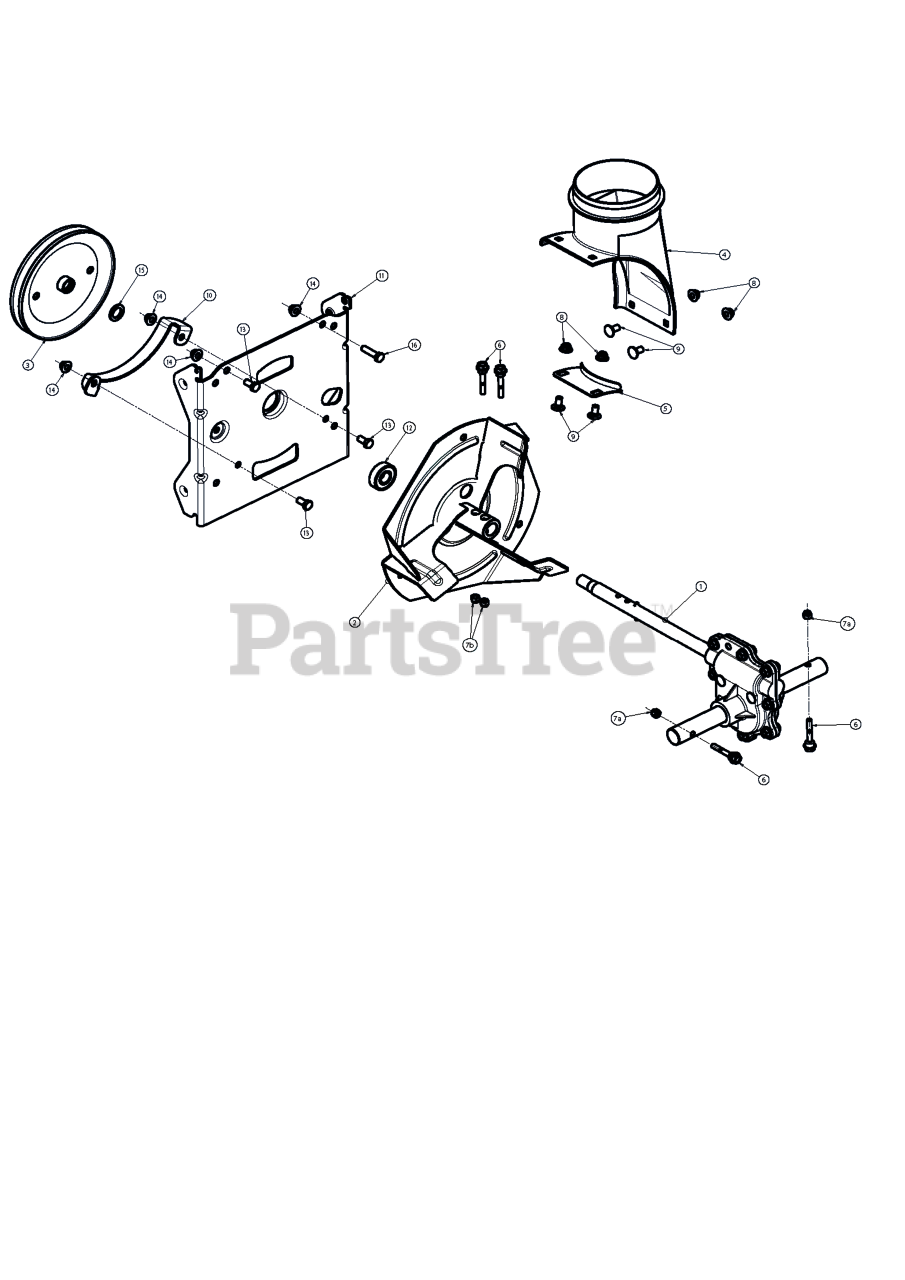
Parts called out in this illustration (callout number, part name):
1	GEAR BOX ASM ALUM
2	IMPELLER.STEEL.SNOW.BLACK
3	PULLEY SCREW ON 7.3
4	CHUTE.DISCHARGE.BASE
5	BRACKET, CORNER DISCHARGE
6	RP_SCREW.1/4-20 X 1-13/16 SHEA
7	LOCKNUT.NYLOC.1/4-20
8	NUT HEX FLG NYLOCK BLK 5_16-1
9	BOLT CARR WAFER BLK 5_16-18 X
10	BRACKET.BELT.KEEPER.LOWER.BLAC
11	BRACKET.AUG.HOUSING.INTER.BLAC
13	BOLT, HEX HEAD 5/16-18
14	NUTNYLOK.FLRANGE.5/16-18
15	WASHER.IMPELLER.PULLEY
16	BOLT.5/16-18X1-1/4 FULL THD
